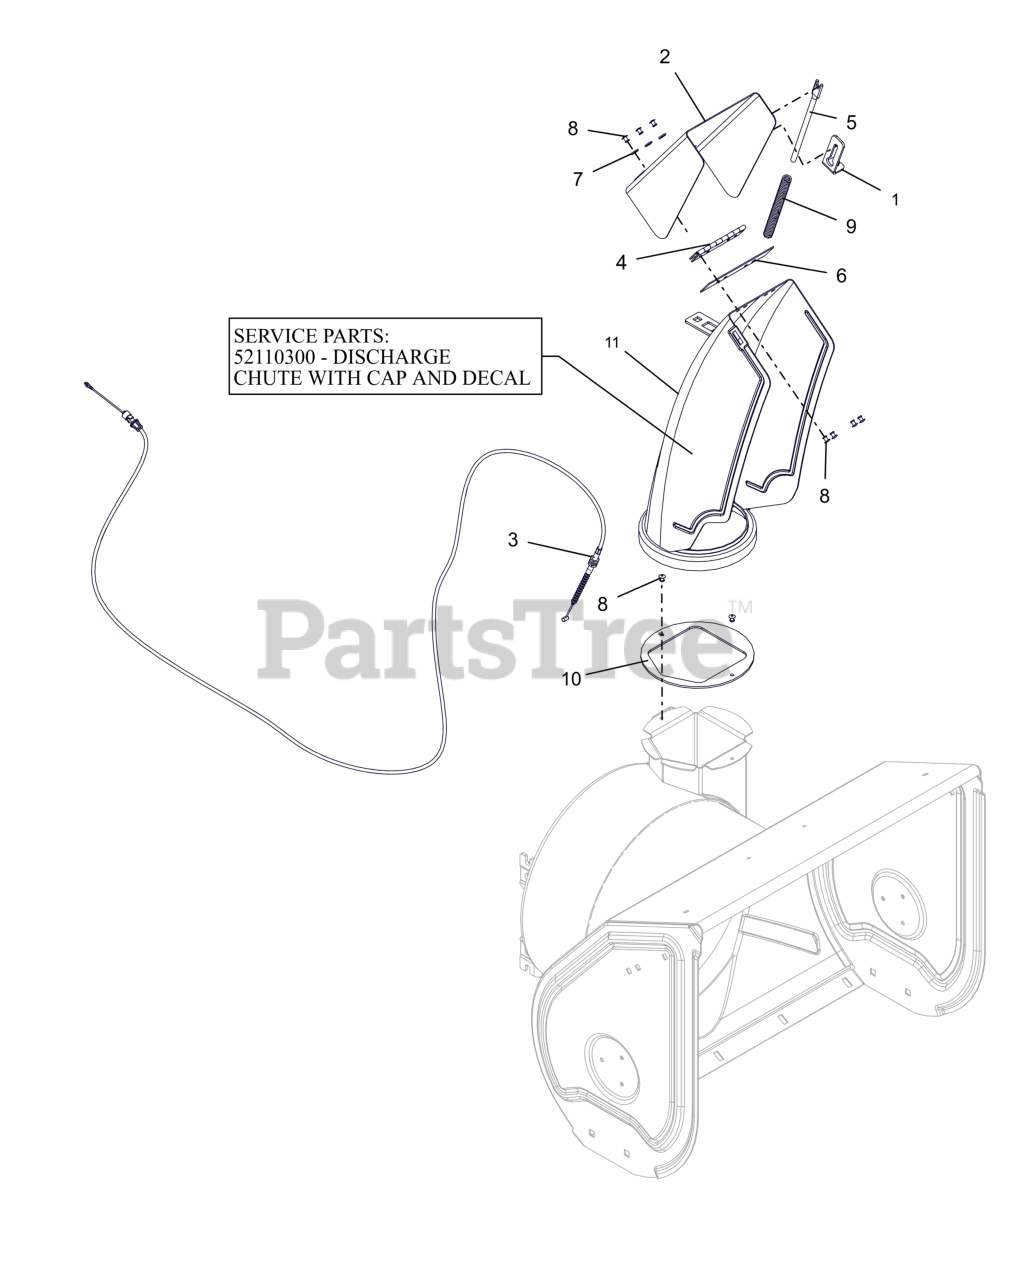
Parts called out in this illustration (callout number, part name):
1	BRACKET, ANCHOR-CHUTE CABLE
2	CAP, LARGE REMOTE W/DECAL
3	CABLE, DEFLECTOR - DELUXE
5	ROD, DEFLECTOR CAP
6	CAP SEAL 5.50
7	WSHR,FLT .196X.500X.066 ZCC
8	RVT, POP .1875 ZCC
9	SG-COMP .08X.40X6.50 14#/IN
10	BAFFLE, DISCHARGE NECK
11	CHUTE,DISCHARGE,RMT,ID
11	CHUTE, DISCHARGE W/CAP
